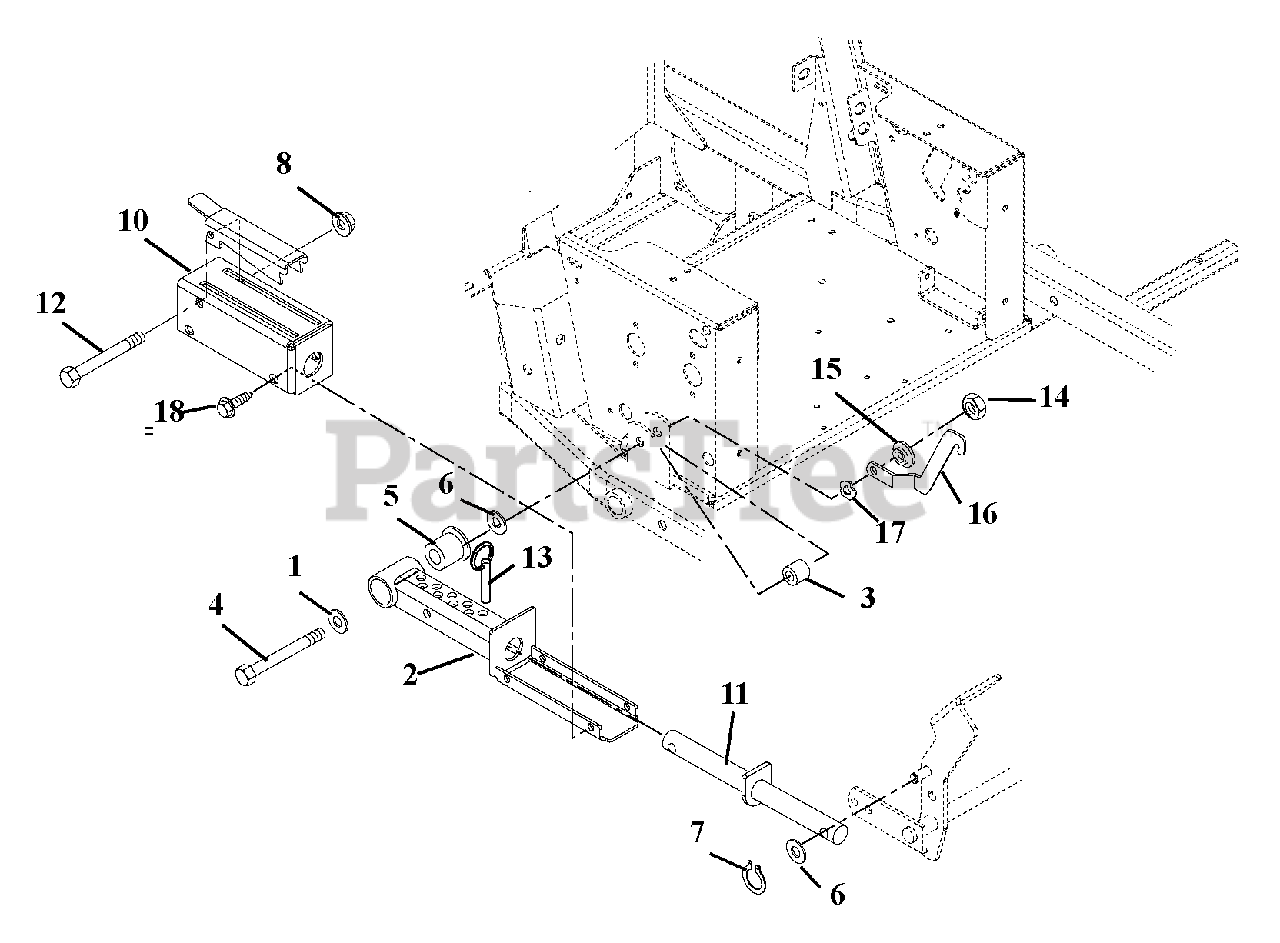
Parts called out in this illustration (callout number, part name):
1	Washer, Flat Steel .531 x 1.250 x .10
2	Weldment, Mechanical Lift
3	Bushing .516 x 1.00 x 1.05
4	Bolt, Hex .50-13 x 5.00 Grade 5
5	Bearing, Pedestal Powdered Metal
6	Washer, Flat Steel .656 x 1.310 x .095
7	Ring, Retaining External .625 x .050
8	Nut, Locking Top Flange .38-16
9	Lock-Up, Mechanical Lift
10	Weldment, Mechanical Lift Cover
11	Weldment, Mechanical Lift Shaft
12	Bolt, Hex .38-16 x 3.25 Grade 5
13	Pin, Spring Ball .375 O.D. x 1.50
14	Nut, Locking Top Flange .50-13
15	Bushing, Flange .515 x .75 x .275 x 1.12
16	Latch, Footboard Hook
17	Washer, Wave .076 x 1.12 x .08
18	Screw, Tapping .38-16 x .50
